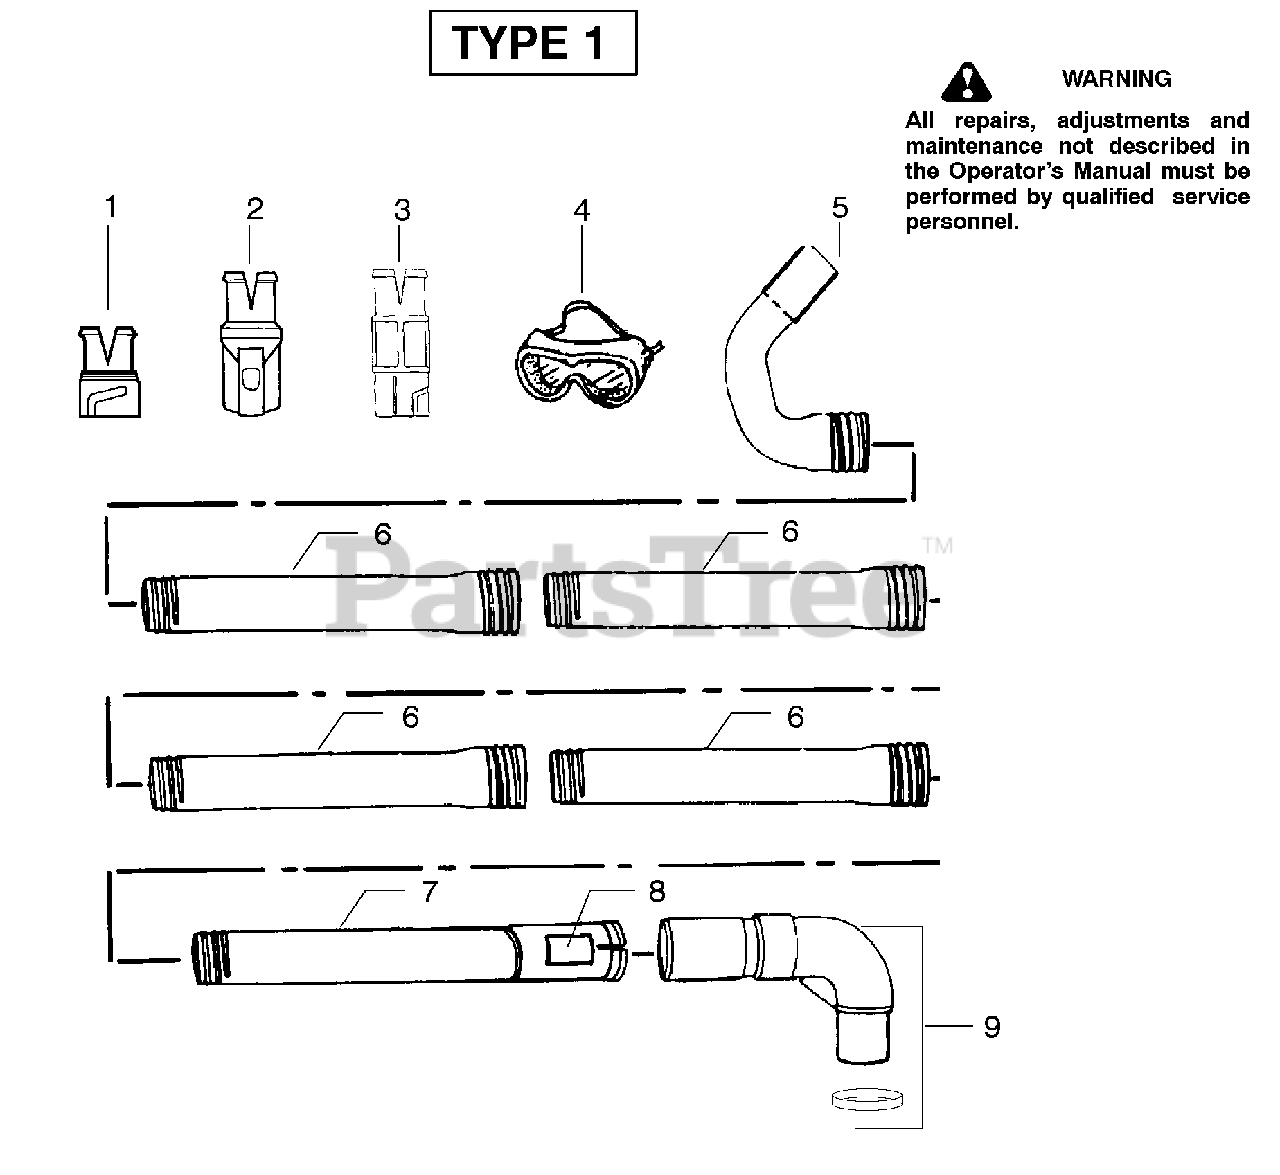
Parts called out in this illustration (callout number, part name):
2	Adapter-Gutter Kit
4	Goggles
6	Tube-Extension
8	Decal-Warning
9	Elbow&Spacer Ring
